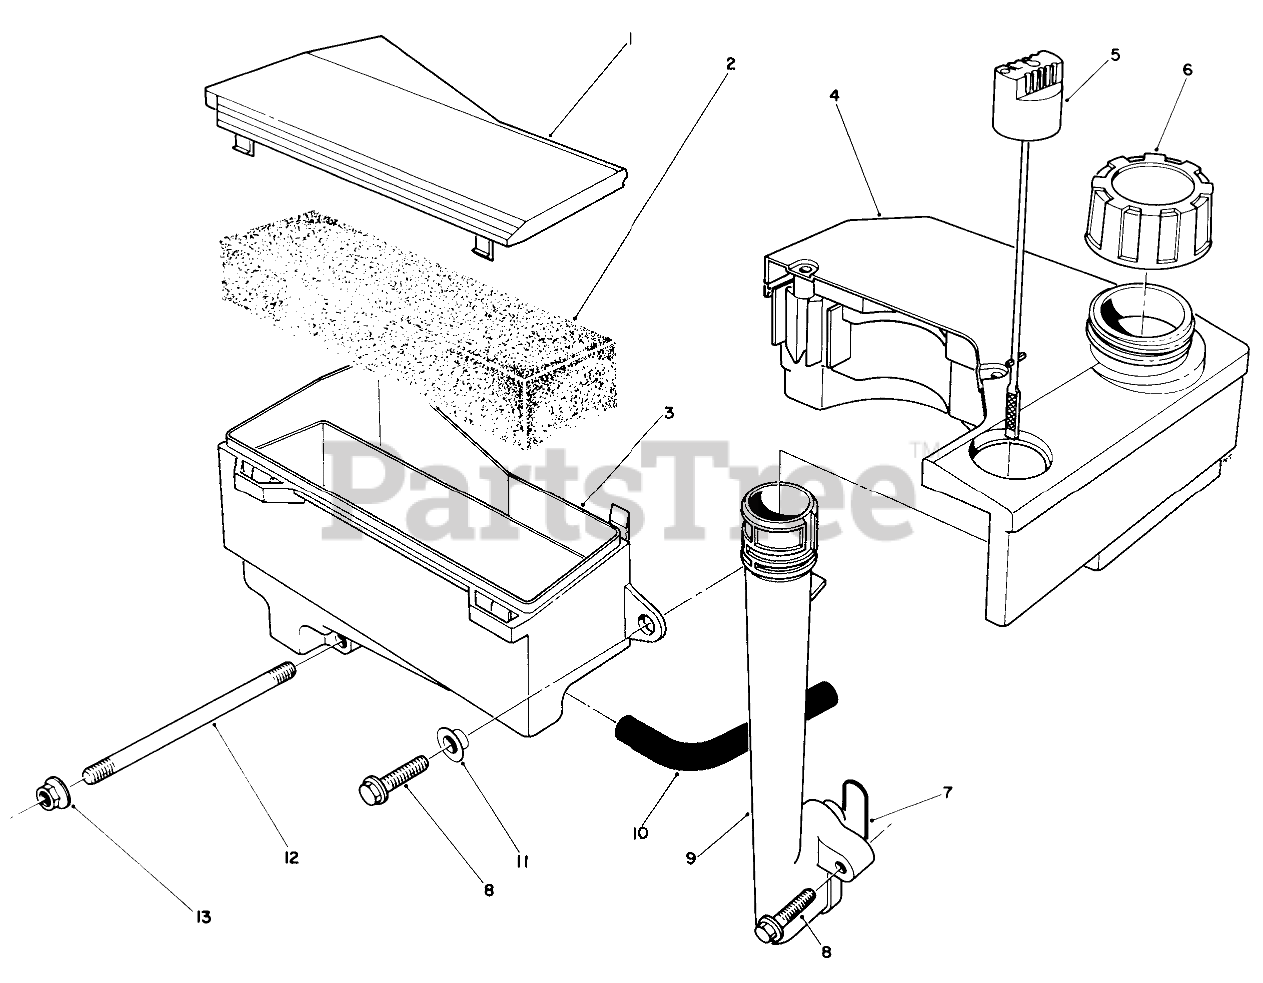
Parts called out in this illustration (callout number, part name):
1	AIR CLEANER CAP
3	Body-Air Cleaner
4	TANK ASM
5	Dipstick
6	GAS CAP ASM
7	O-RING
11	SPACER
12	Stud-Carburetor
